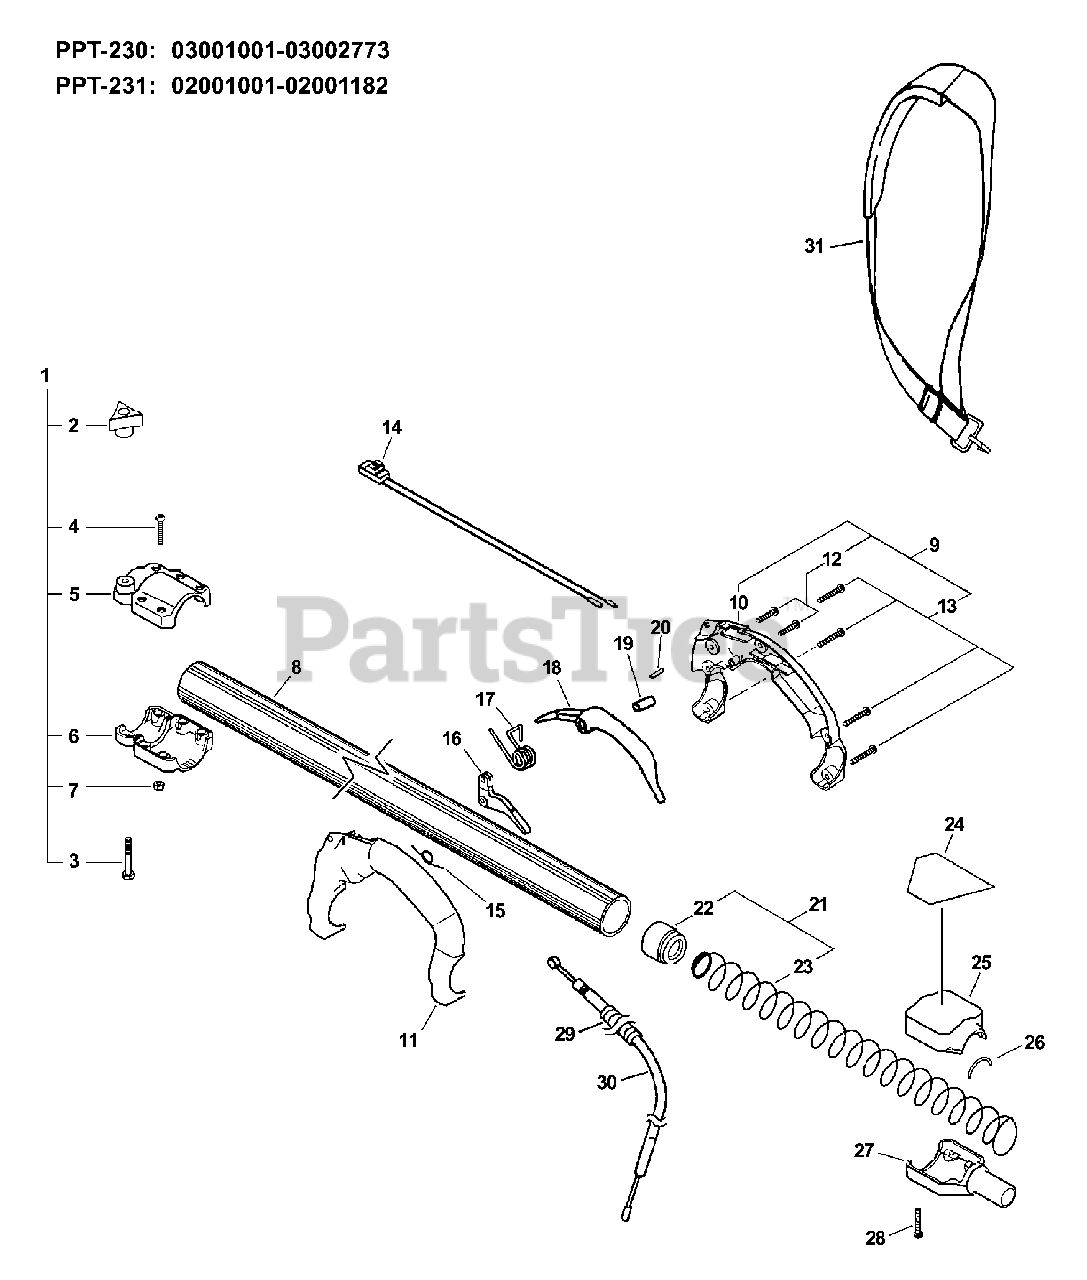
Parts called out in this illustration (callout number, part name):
1	CLAMP ASSY
2	THUMBSCREW
4	SCREW, TORX 10-24 UNC 1-1/4
5	COLLAR, UPPER
6	COLLAR, LOWER
7	NUT, LOCK 10-24 UNC
8	PIPE, MAIN
9	HANDLE SET, REAR
10	CONTROL HANDLE - LEFT
11	HANDLE, RIGHT REAR
12	SCREW, TORX
13	SCREW, TORX 10-24 UNC 1-1/4
14	SWITCH, ON-OFF
15	SPRING, TORSION
16	TRIGGER, THROTTLE
17	SPRING, TORSION
18	LOCKOUT, THROTTLE
19	COLLAR 5.08×14.5
20	PIN, LOCATING 0.17 OD×0.75 L
21	BUSHING ASSY, FLOATING
22	BUSHING, FLOATING
23	SPRING, COMPRESSION
24	LABEL, CAUTION
25	CAP, MAIN PIPE
27	ADAPTER, LOWER SHAFT TUBE
28	SCREW, TORX 10-24 UNC 1-1/4
29	TUBE, FLEXIBLE
30	CABLE, THROTTLE
31	STRAP ASSY, SHOULDER
